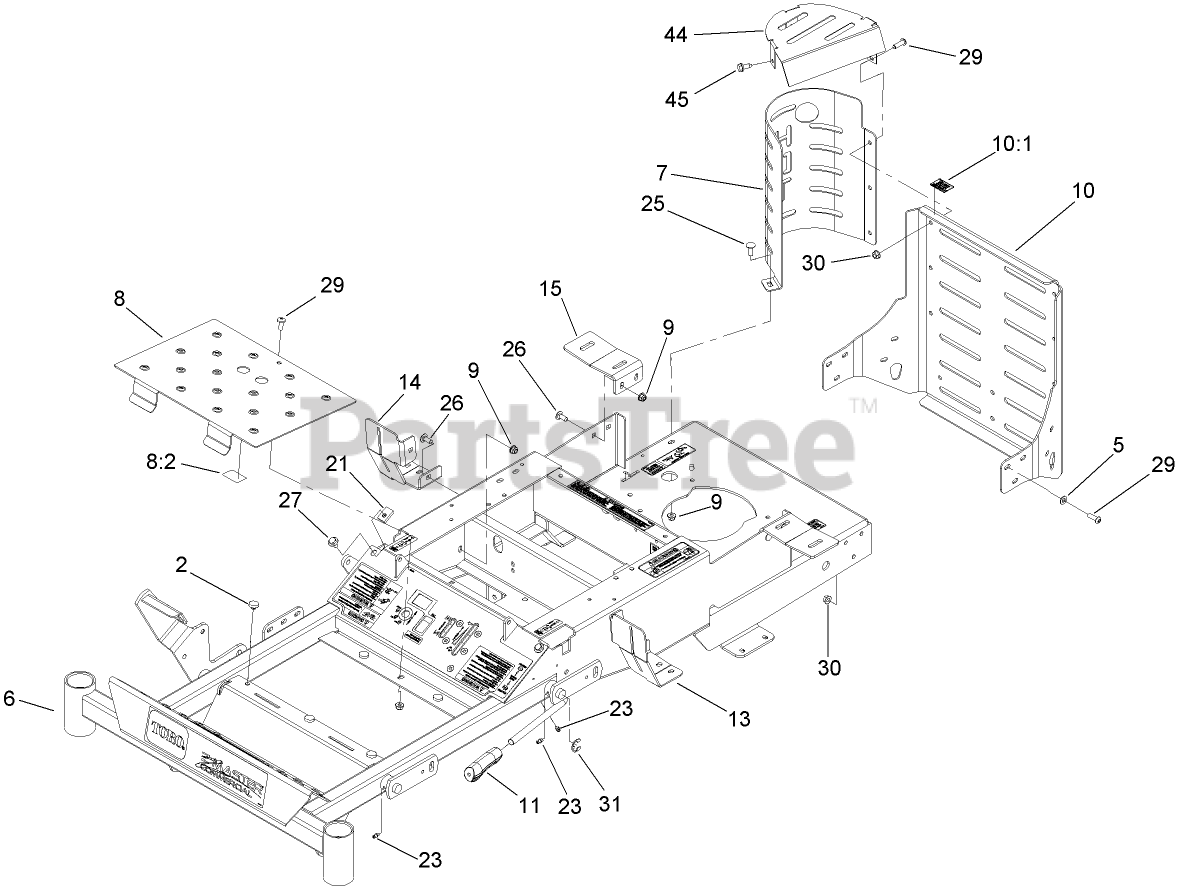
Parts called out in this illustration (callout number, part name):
2	BUMPER
5	WASHER-PLAIN
6	FRAME DECAL ASM
7	GUARD-MUFFLER
8	FLOOR PAN ASM
8:2	DECAL-GUARD
9	NUT-HF, NI
10	REAR GUARD ASM
10:1	DECAL-MUFFLER
11	GRIP-LEVER, BRAKE
13	MOUNT-TANK, FUEL (LH)
14	MOUNT-TANK, FUEL (RH)
15	BRACKET-FUEL TANK, REAR
21	STOP-MOTION
23	FITTING-GREASE
25	SCREW-CARR
26	SCREW-CARR
27	SCREW-HHF
29	SCREW-HSBH
30	NUT-HF
31	E-RING
44	SHIELD-HEAT, CE
45	SCREW-HWHTF
